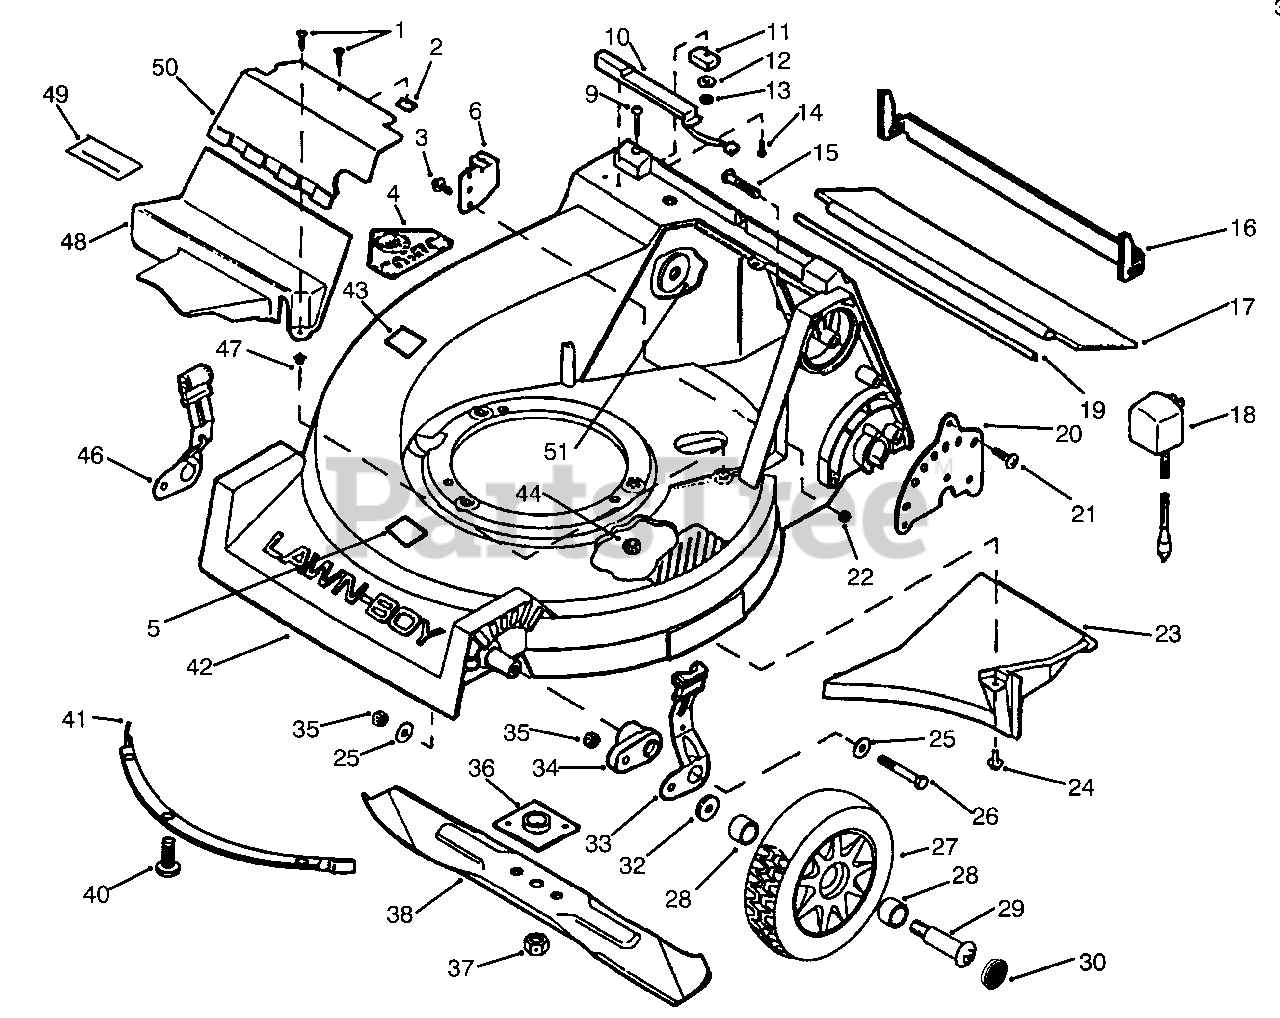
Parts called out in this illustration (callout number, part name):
2	Speednut
4	Decal-Blade Warning
5	Decal-Spark Plug
6	Anchor-Cable
10	Switch-Lock, Bag
11	Assembly-Magnet
12	Washer-Lock
15	Bolt-Mounting, Handle
16	Shield-Housing
17	Shield-Trailing
18	Charger-Battery
19	Rod-Shield, Trailing
20	Plate-Height Adjust
21	Screw-Plate to Housing
22	Nut-Anchor, Cable
24	Screw-Baffle to Housing
27	Assembly-Wheel & Tire (Incl. Ref. #28)
29	Bolt-Shoulder
31	Assembly-Wheel & Tire
33	Assy.-Spring Arm, L.H.
34	Arm-Front, Height Adjust
35	Nut (Thin)
36	Assembly-Collar & Plate
37	Nut-Blade
38	Blade-21"
41	Baffle-Front
43	Decal-Sound Emission
44	Nut-Lock
46	Assy.-Spring Arm, R.H.
47	Grommet
48	Cover-Drive) Lower
49	Decal-Warning
50	Cover-Drive, Upper (Incl. Ref. #49)
51	Washer-R.H. Handle Mtg.
